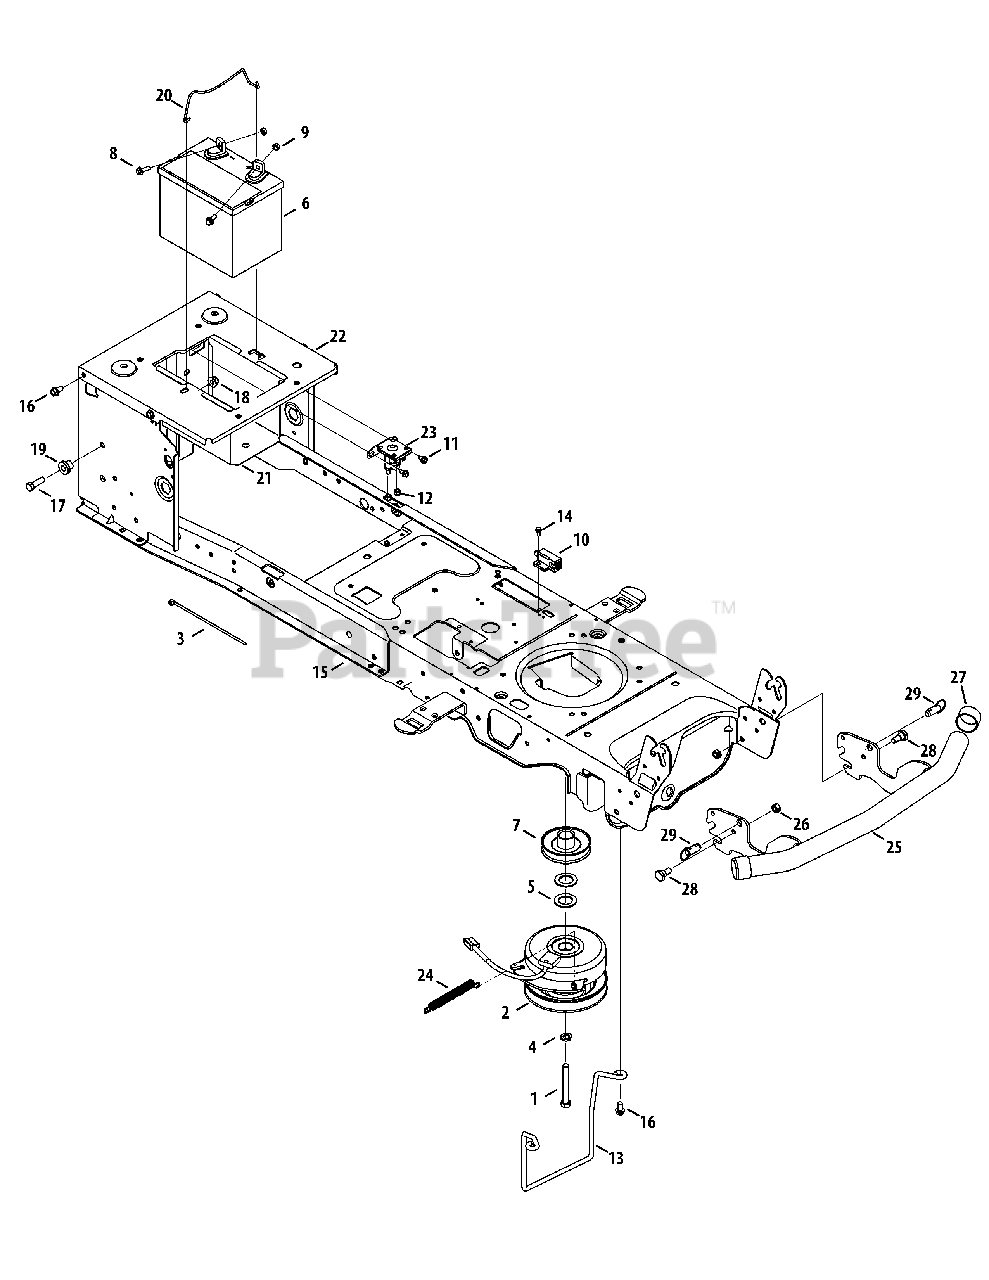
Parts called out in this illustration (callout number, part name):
1	Hex Screw, 7/16-20, 3.50, Gr5, Lock
2	Clutch, Electric PTO
3	Cable, Tie, 3/16 X .05 X 7.4
4	Washer, Lock, 7/16 , Regular Duty
5	Washer, Flat, 1.031 X1.620 X.095
7	Engine Pulley, Electric PTO
8	Hex Flange Screw, 1/4-20, .75, Gr5
9	Nut, Sems, 1/4-20
10	Switch, Interlock
11	Screw, Self-tapping, 1/4-20, 0.375
12	Nut, Flange Lock, 1/4-20, Nylon
13	Rod, Keeper
14	Screw, Shoulder, #10-32, .50
15	Frame Assembly, Lower
16	Screw, Self-tapping, 5/16-18, .750
17	Hex Screw, 3/8-16, 1.50, Gr2
18	Nut, Flange Lock, 3/8-16, Nylon
19	Spacer, Shoulder, .38 X 1.0 X .70
20	Rod, Battery
23	Solenoid, 12V, 100 Amp, 4 term
24	Spring, Extn, .38 Dia X 3.25
26	Nut, Hex Lock, 3/8-16, GrB
27	Cap, Bumper
28	Bolt, Shoulder, .496 x .336, 3/8-16
29	Pin, Quick Release, 1/2 Dia x .50
